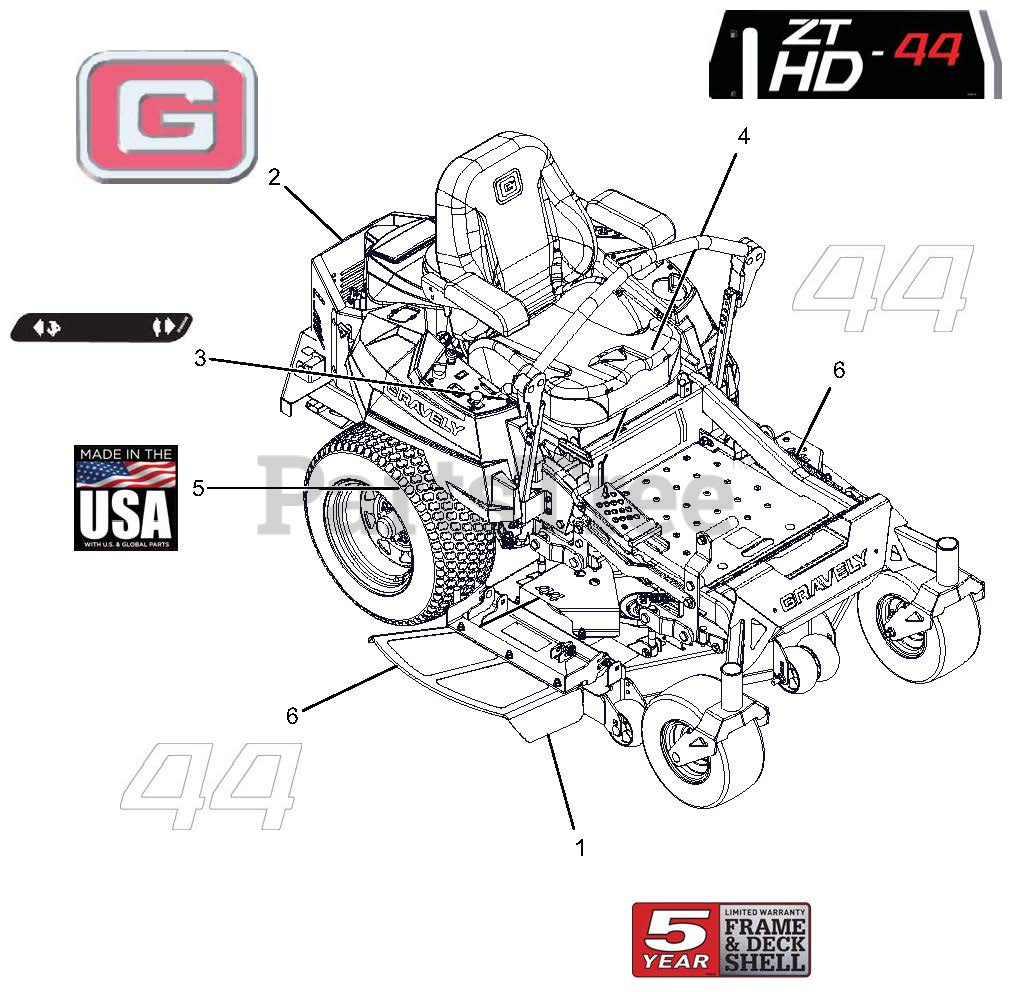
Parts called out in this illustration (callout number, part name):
1	DECAL,DECK WARRANTY-FAB GRVLY
2	DECAL, GRAVELY BRAND
3	DECAL, DASH DECAL
4	DECAL - 44HD
5	DECAL, MADE IN USA
6	DECAL - 44"
